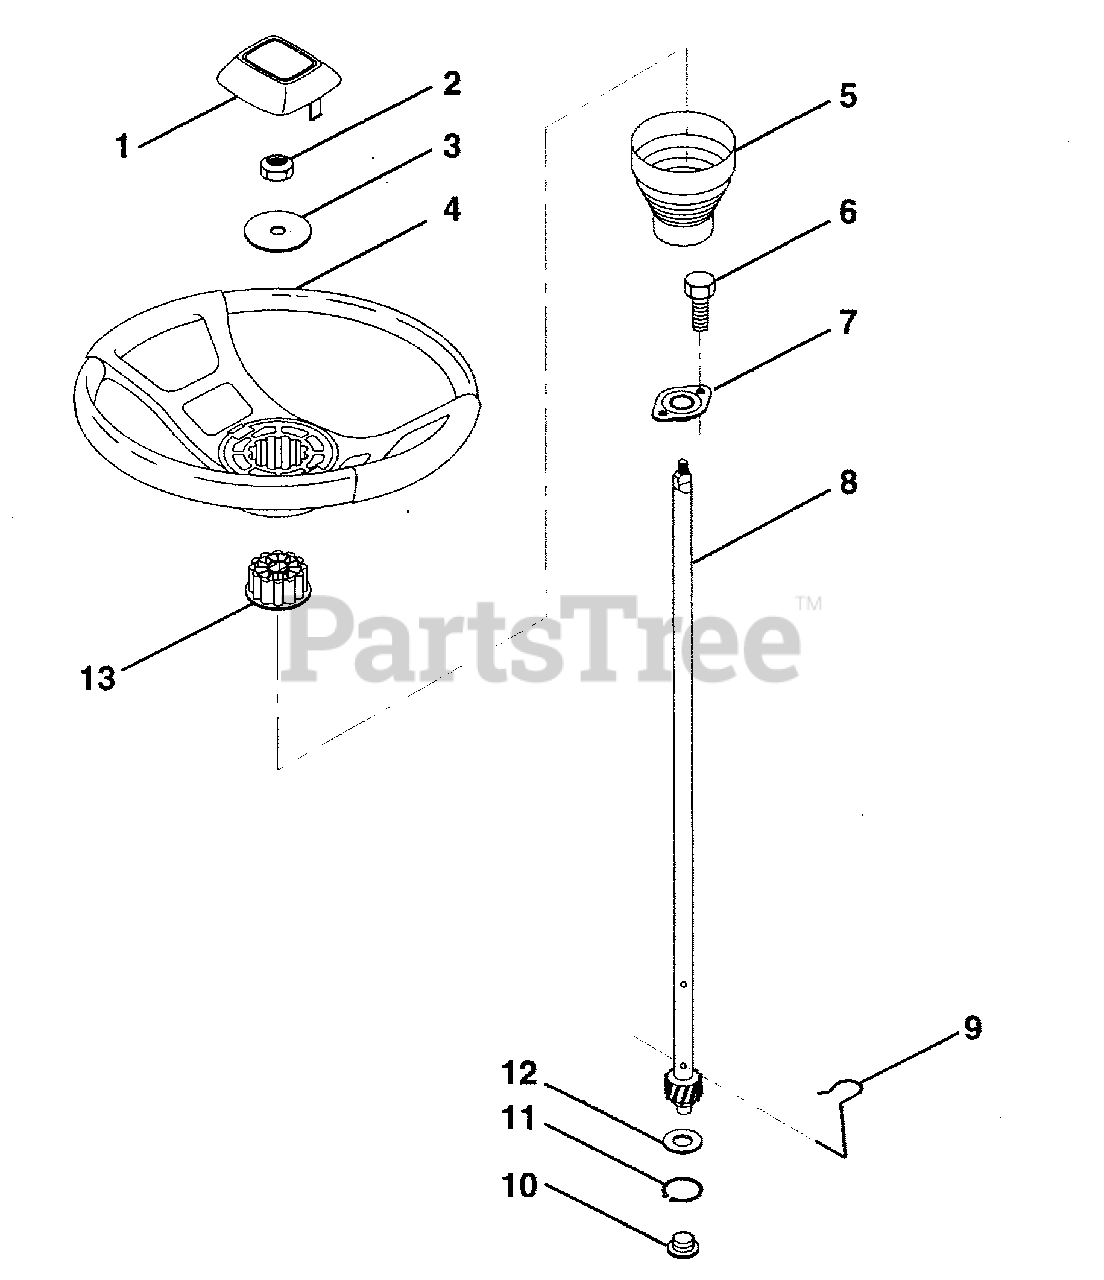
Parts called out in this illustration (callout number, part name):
1	Insert, Steering Wheel
2	Locknut 3/8-24 UNF
3	Washer 12l32 x 2-318 x 8 Gauge
4	Steering Wheel
5	Sleeve, Steering
6	Screw, Hex #lo-16 x l/2 TY-B
7	Bushing, Steering
8	Shaft, Steering
9	Clip, Steering
10	Bushing, Lower, Steering
11	Ring, Retaining
12	Washer 21/32 x 1 x 16 Gauge
13	Adaptor, Steering Wheel
